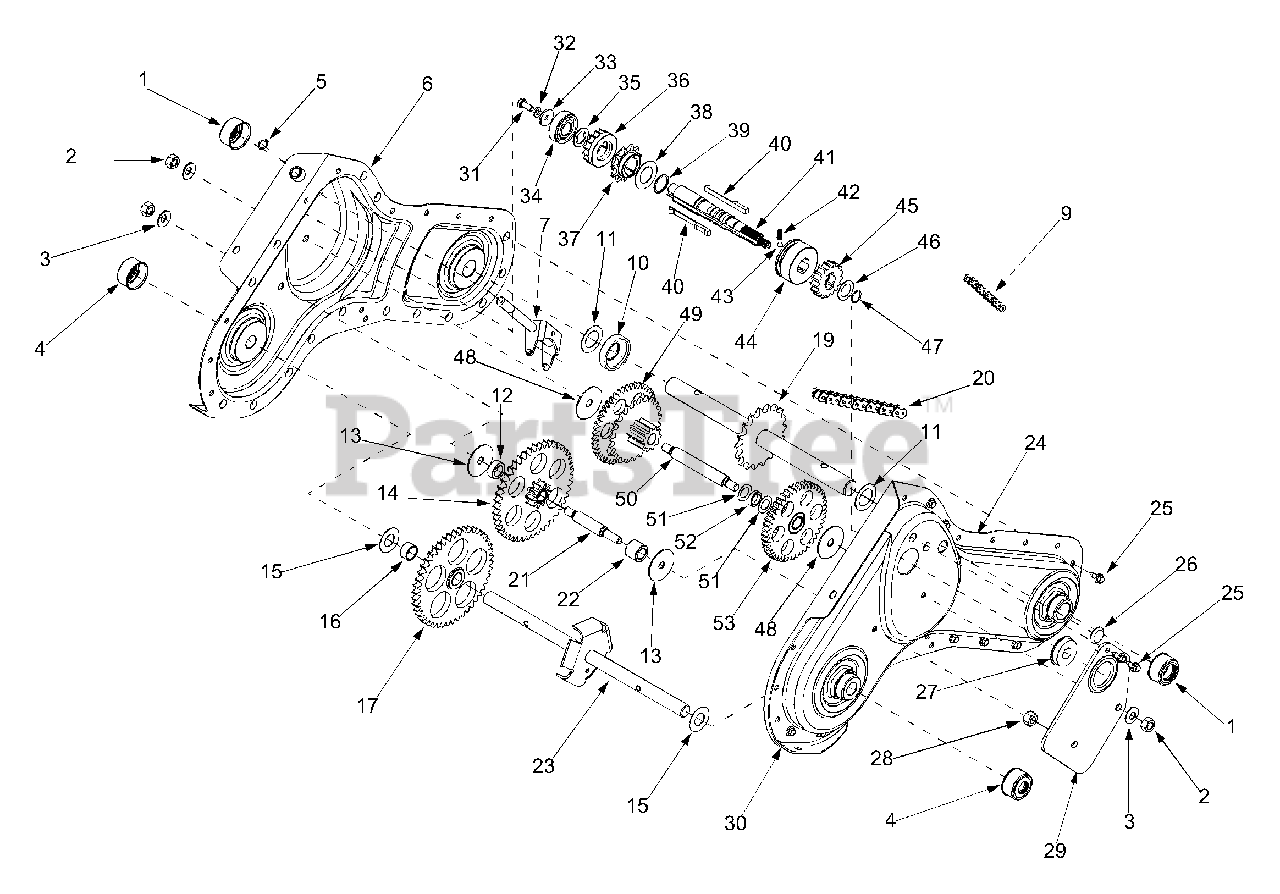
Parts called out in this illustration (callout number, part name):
1	Shaft Seal 1.0 Dia
2	Hex Nut 7/16-20
3	Bell Washer.45 ID x 1.0 OD
4	Shaft Seal.75 Dia
5	Snap Ring.50 Dia
7	Shift Assembly
9	Chain - #41 1/2" Pitch x 30 Links
10	Space 1.0 ID x 2.0 OD
11	Thrust Washer 1.03 ID x 1.62 OD
12	Spacer.635 ID x 1.0 OD
13	Thrust Washer.445 ID x 1.92 OD
14	Idler Gear Assembly
15	Flat Washer.760 ID x 1.50 OD
16	Spacer.735 ID x.886 OD
17	Spur Gear 46T
19	Tine Shaft Assembly 18T
20	Chain - #50 5/8" Pitch x 52 Links
21	Jack Shaft 5/8 Dia. X. 2.06 Lg
22	Spacer.635 ID x 1.0 OD
23	Wheel Shift Assembly
27	Ball Bearing w/Snap Ring
28	Hex Patch L-Nut 7/16-20
30	Chain Case Gasket
31	Hex Cap Screw 1/4-20 x.625
32	Lock Washer 1/4
33	Flat Washer.281 ID x.875 OD
34	Ball Bearing
35	Flat Washer
36	Spur Gear 16T
37	Sprocket 11T #41 Chain
38	Flat Washer.88 ID x 1.50 OD
39	Retainer Ring
40	Clutch Key
41	Drive Shaft
42	Compression Spring
43	Detent Ball
44	Clutch Collar
45	Spur Gear 17T
46	Flat Washer.69 ID x 1.06 OD
47	Wire Ring
48	Thrust Washer.445 ID x 1.9 OD
49	Intermediate Gear Assembly
50	Jack Shaft
51	Flat Washer.625 ID x 1.0 OD
52	Spacer.635 ID x.86 OD
53	Tine Drive Assembly
